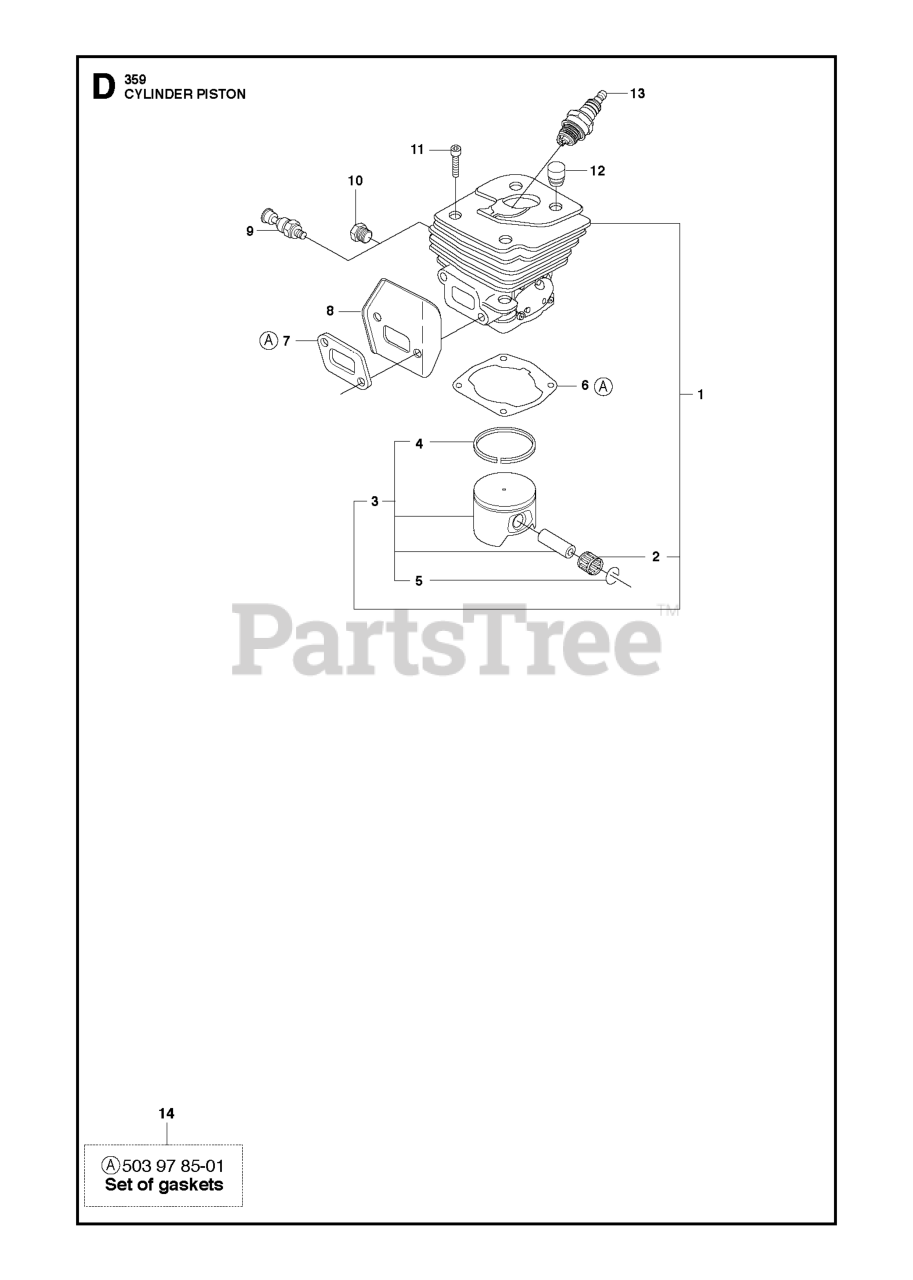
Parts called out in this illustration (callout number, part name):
1	%CYLINDER
2	SUPPORT BUSHING
3	%PISTON
4	%PISTON RING
5	WRIST PIN CLIP
8	HEAT DEFLECTOR
9	DECOMPRESSION VALVE
10	CYLINDER PLUG
11	SCREW MC6S 5X25
13	SPARK PLUG RCJ7Y
14	GASKET SET
